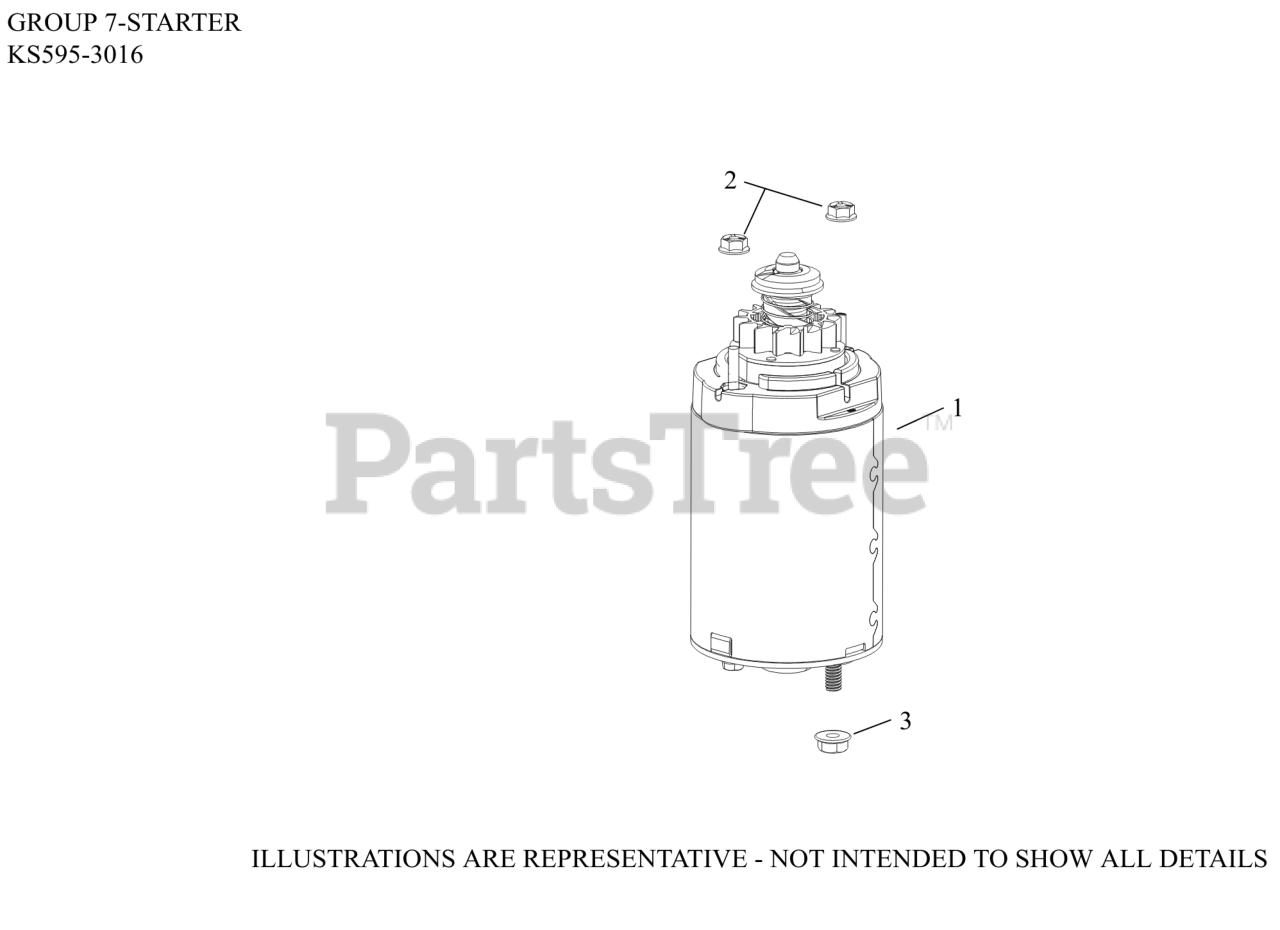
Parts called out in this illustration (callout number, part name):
1	STARTER, ASSY
2	NUT, HEX FLANGE LOCK (10-24)
3	NUT, FLANGE 1/4-20
